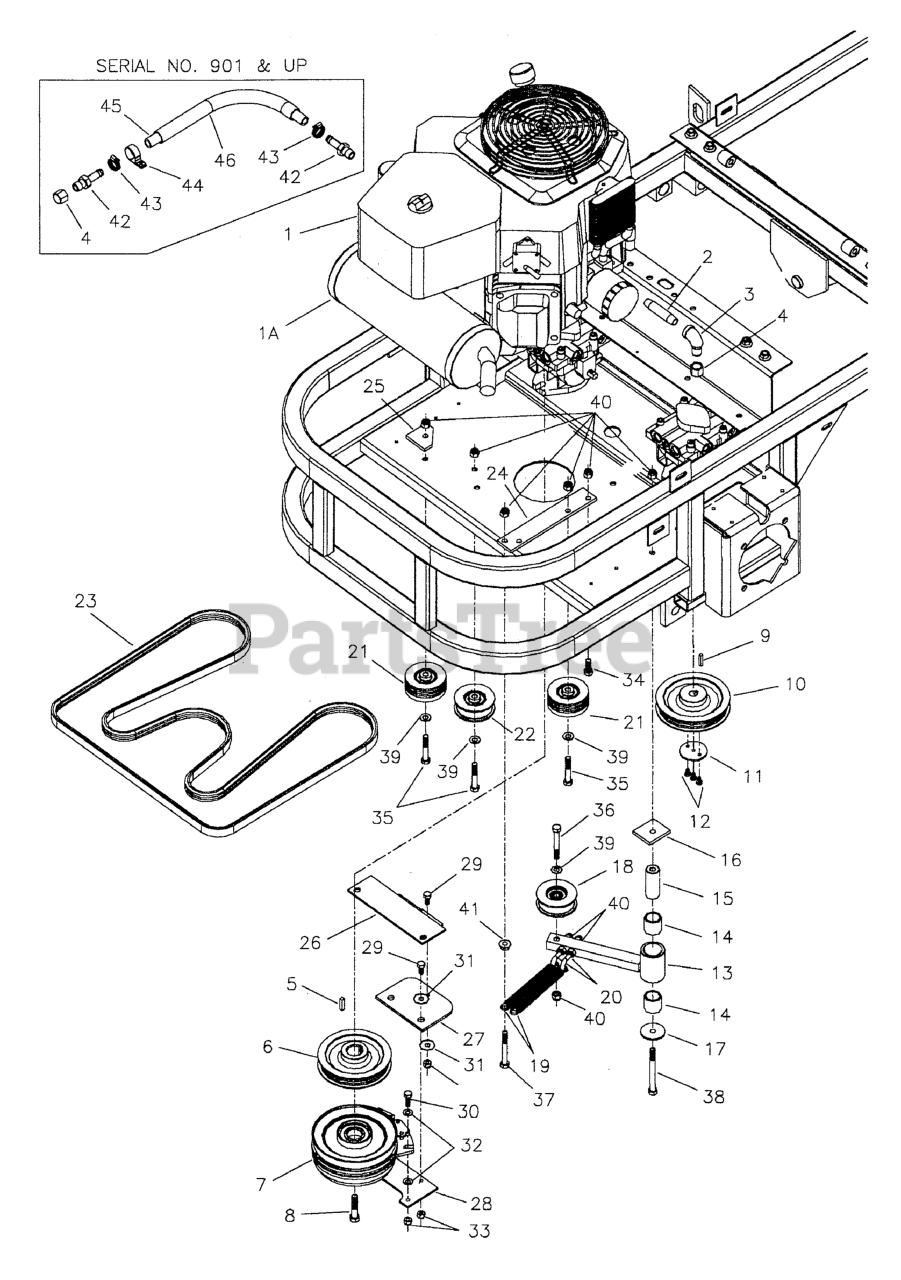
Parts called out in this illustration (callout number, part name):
1	ENGINE, Kohler
2	NIPPLE, 3/8" NPT x 3"
3	STREET L, 3/8" NPT
4	CAP, 3/8 NPT
5	KEY, 1/4 SQ. X 1
6	PULLEY, Crankshaft
7	CLUTCH, Electric
8	CRANKSHAFT BOLT, 7/16 x 2
9	KEY, 5MM SQ. x 25MM w/ Round Ends
10	PULLEY, Pump Drive
11	WASHER, Pulley Retaining
12	BOLT, M6 x 10MM
13	IDLER ARM ASSEMBLY, Complete
14	BUSHING, Brass
15	SPACER, .39 X 1.00 X 2.55, SS
16	SPACER, Idler Pivot
17	WASHER, 3/8 x 1-3/4
18	HYDRO IDLER PULLEY ASSEMBLY
19	SPRING, Extension
20	SCREW HOOK
21	IDLER PULLEY ASSEMBLY
22	BACKSIDE IDLER PULLEY ASSEMBLY
23	BELT, Pump Drive
24	ANCHOR, Spring Idler
25	SUPPORT, Pulley
26	MOUNT, Clutch Anchor
27	CLUTCH ANCHOR PAD
28	ANCHOR, Clutch
29	BOLT, 5/16-18 X 3/4 GD5
30	BOLT, 5/16-18 X 1 GD5 YZ
31	WASHER, 5/16" Fender
32	WASHER, 5/16" SAE
33	NUT, 5/16-18 Hex Nylon Lock
34	BOLT, 3/8-16 X 1" GD5 CZ
35	BOLT, 3/8-16 X 2-1/4" GD5 CZ
36	BOLT, 3/8-16 X 2-3/4" GD5 CZ
37	BOLT, 3/8-16 X 3" GD5 CZ
38	BOLT, 3/8-16 X 4" GD5 CZ
39	WASHER, 3/8 SAE
40	NUT, 3/8-16 HEX NYLON LOCK
41	NUT, 3/8-16 Hex Serrated Flange
42	FITTING, 3/8NPT-1/2" Hose, Straight
43	CLAMP, #6 Hose
44	CLAMP, Vinyl
45	HOSE, 16" Long
46	WIRE LOOM, 14"
